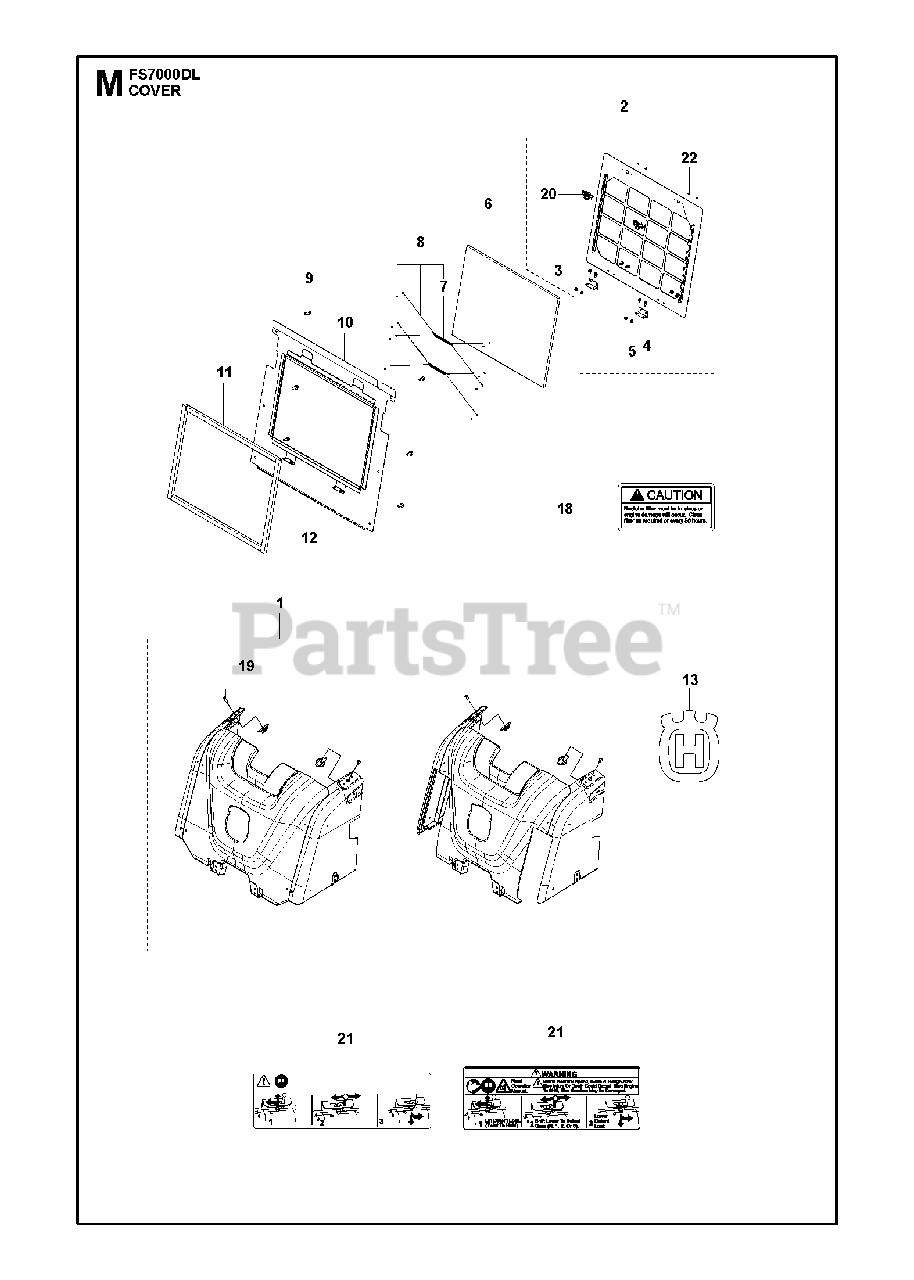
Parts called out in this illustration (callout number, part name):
5	HEXAGON NUT FLANGE
21	DECALEU Not Included in Kit
21	DECALUS Not Included in Kit
